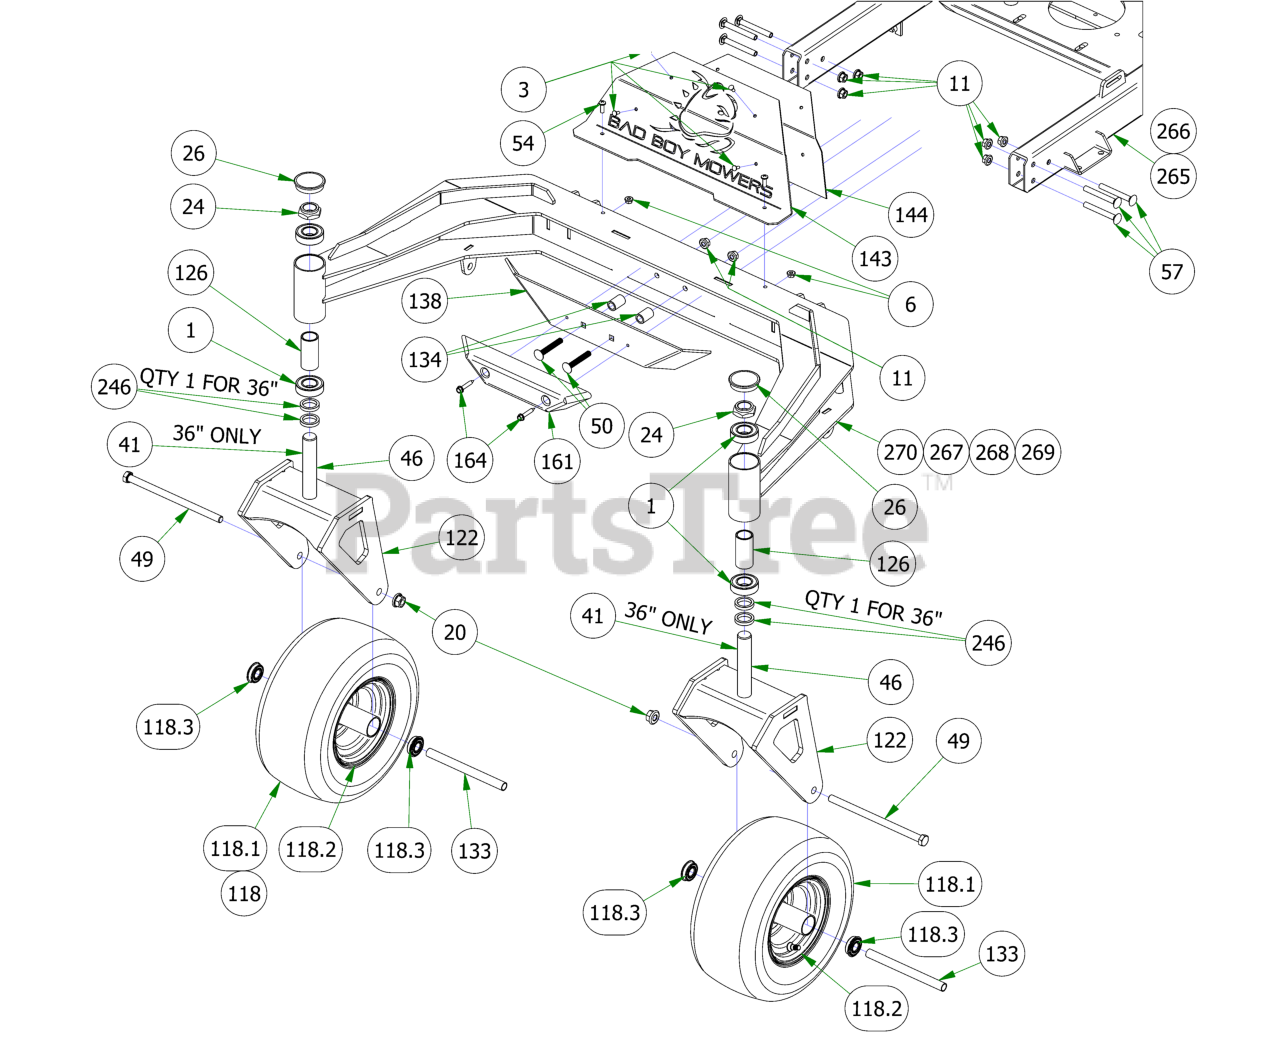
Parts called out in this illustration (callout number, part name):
1	1641 BEARING W/2 CONTACT RUBBER SEALS
3	3/16 Rivet for .126-.25 THK
6	1/4-20 NYL INSERT FLANGE LOCKNUT ZINC
11	3/8-16 NYLON INSERT FLANGE LOCKNUT (GR.F) ZINC
20	1/2-13 NYLON INSERT FLANGE LOCKNUT ZINC
24	1"-14 NYLON INSERT JAM LOCKNUT ZINC
26	2017 Bearing Cover
41	1"-14 X 5 HEX CAP SCREW (GR.8) ZINC YELLOW
46	1"-14 X 5-1/2 HEX CAP SCREW (GR.8) ZINC YELLOW
49	1/2-13 X 8-1/2 HEX CAP SCREW (GR.5) ZINC
50	3/8" x 2 1/2" Carriage Bolt
54	1/4"-20 x 3/4 Black Oxide 18-8 Stainless Pan Head
57	3/8-16 X 3 CARRIAGE BOLT ZINC GR5
118	13 x 6.50 - 6 Tire and Wheel
118.1	13 x 6.50 - 6 Tire
118.2	Front Tire Rim
118.3	Ball Bearing w/Retainer, 99502H-NR, .625 Bore x 1.375 OD x .4375 Width
122	2019 Stand-on Front Fork Weldment
126	2016 Front Bearing Spacer
133	Front Wheel Spanner
138	2019 Stand On Front Bumper Plate
143	Exhaust Shield Plate 2019 Stand On
144	Exhaust Backer Plate 2019 Stand On
161	Bumper EZT
164	1/4-14 X 1-1/2 HEX WASHER UNSLOT TEK/3 ZINC
246	1.02 ID X 1.38 OD X .250 THK SPACER ZINC
265	2019 Stand On Frame
266	2020 36" Stand On Frame
267	2020 36" Stand On Front End Weldment
268	48" Stand On Front End 2019 Welded Assembly
269	54" Stand On Front End 2019 Welded Assembly
270	61" Stand On Front End 2020 Welded Assembly
